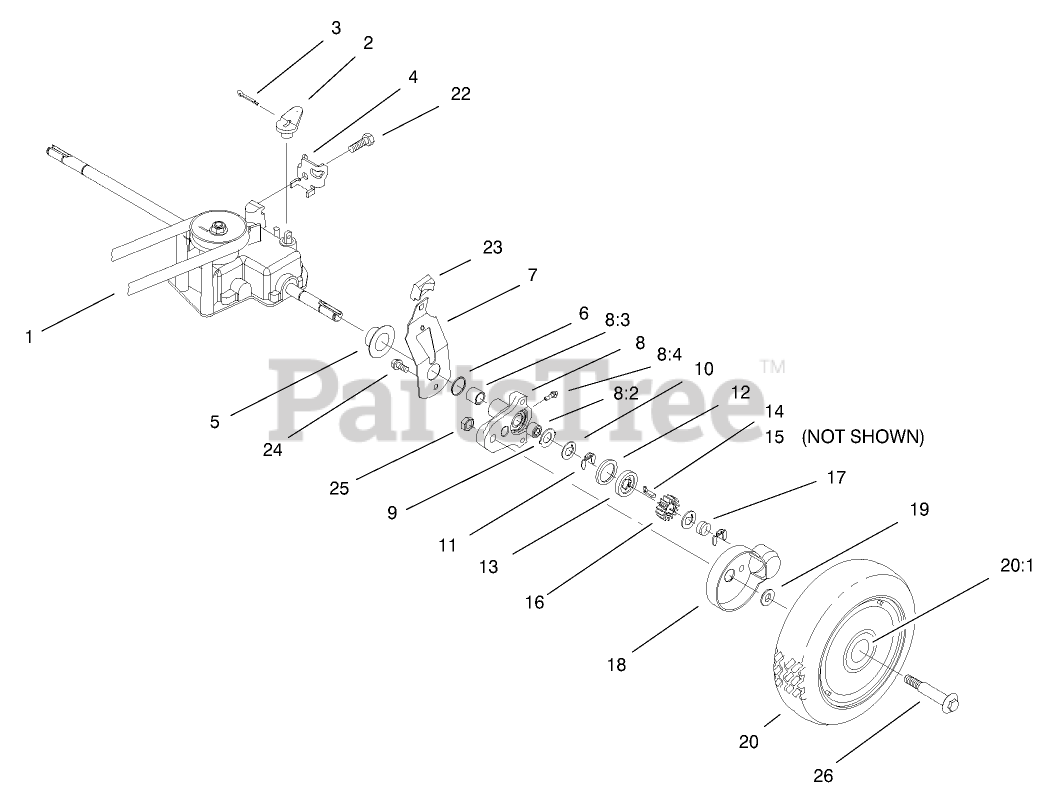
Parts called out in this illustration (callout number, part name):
1	V-BELT
2	LEVER-SHIFT
3	PIN-COTTER
4	CLAMP-CABLE
5	CAP-END
6	O-RING
7	SPRING ARM ASM
8	PIVOT ARM ASM
8:2	BUSHING
8:3	BUSHING
8:4	FITTING-GREASE
9	WASHER-ARM, PIVOT
10	WASHER-THRUST, KEYED
11	RING-RETAINING,CLIP
12	RING-FRICTION
13	WASHER-CLUTCH
14	KEY-ROCKING, LH
15	KEY-ROCKING, RH
16	GEAR-PINION
17	SPRING-COMPRESSION
18	COVER-WHEEL
19	SPACER-COVER, WHEEL
20	WHEEL TIRE ASM (SP)
20:1	BUSHING
22	SCREW-HWHTF
23	KNOB-ARM
24	SCREW-HWH
25	LOCKNUT
26	BOLT-SHOULDER
